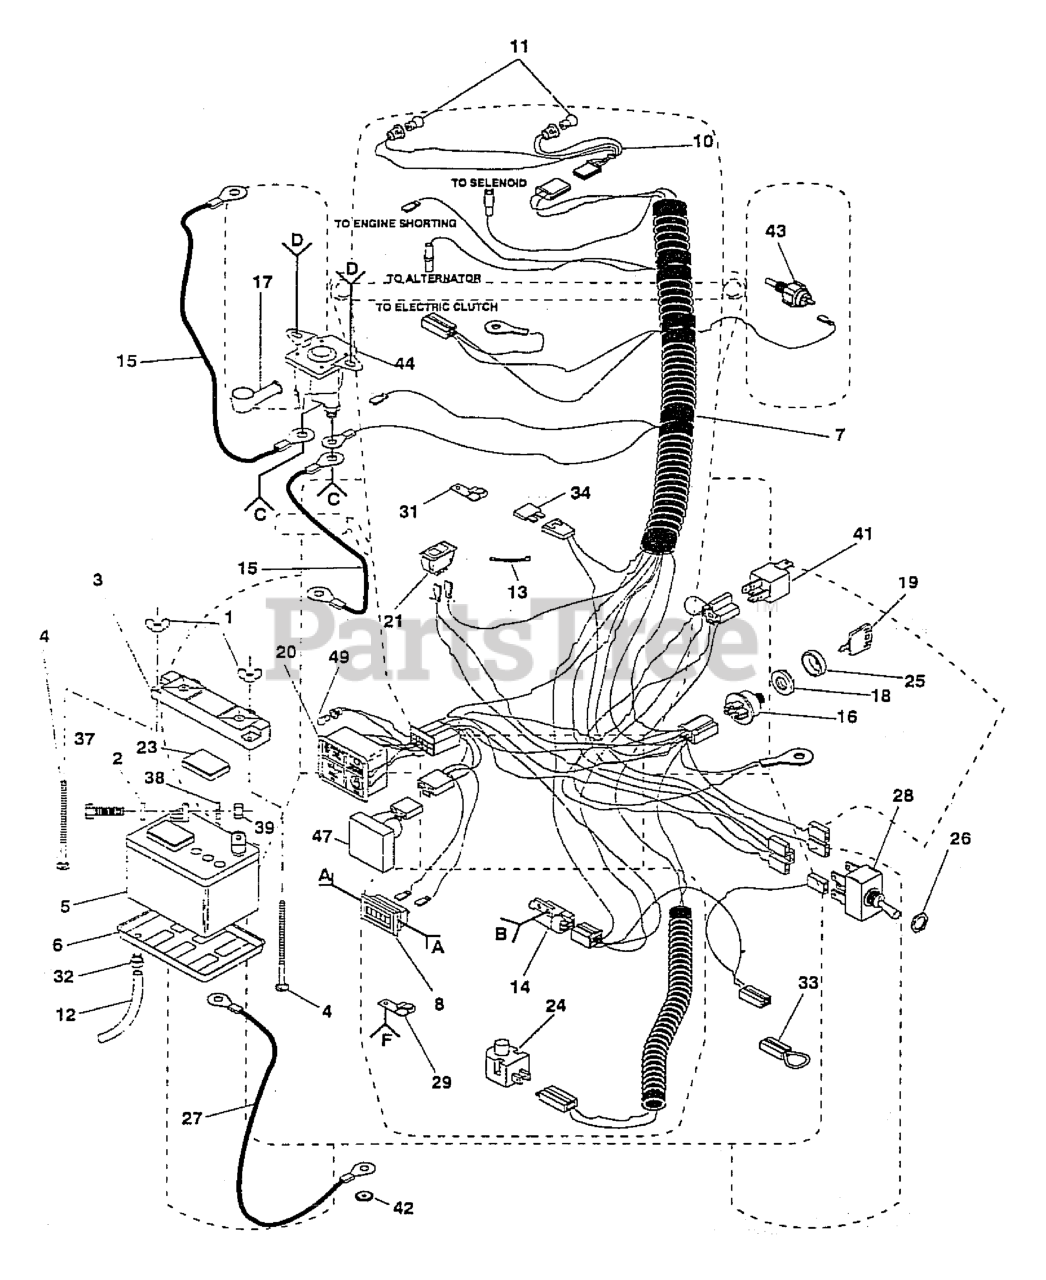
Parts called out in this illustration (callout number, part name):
1	WING NUT
2	WASHER
3	TERMINAL GRD YTV
5	BATTERY
6	BATTERY TRAY T
7	HARNESS IGNITION
8	HOUR METER T
11	BULB-LIGHT T
12	BATT DRAIN TUBE T
13	TIE GUIDE
14	SWITCH INTERLOCKT
15	CABLE-BATTERY YTV
16	SWITCH YTV
17	TERMINAL COVER
18	NUT IGNITION
19	KEY.MOLDED.GENERIC
20	INDICATORLIGHTT
23	CAP BATTERY NLA
24	RP.SWITCH.PLUNGER.NC.GRAY
25	COVER KEY IGNITIO
26	HEX NUT T
27	CABLE T
28	SWITCH,PTO
29	CLIP T NLA
31	CLIP T
32	HOSE CLAMP T
33	LOOP-WIRE YTV
37	BOLT.HEX.1/4.X.3/4.DICHROMATE
38	LOCKWASHER
39	NUT
41	RELAY.ASSY.T
42	LOCKWASHER
43	SWITCH OIL SENSOR
44	SOLENOID KIT
47	SENSOR LOW VOLTAGE
49	BULB LIGHT T
